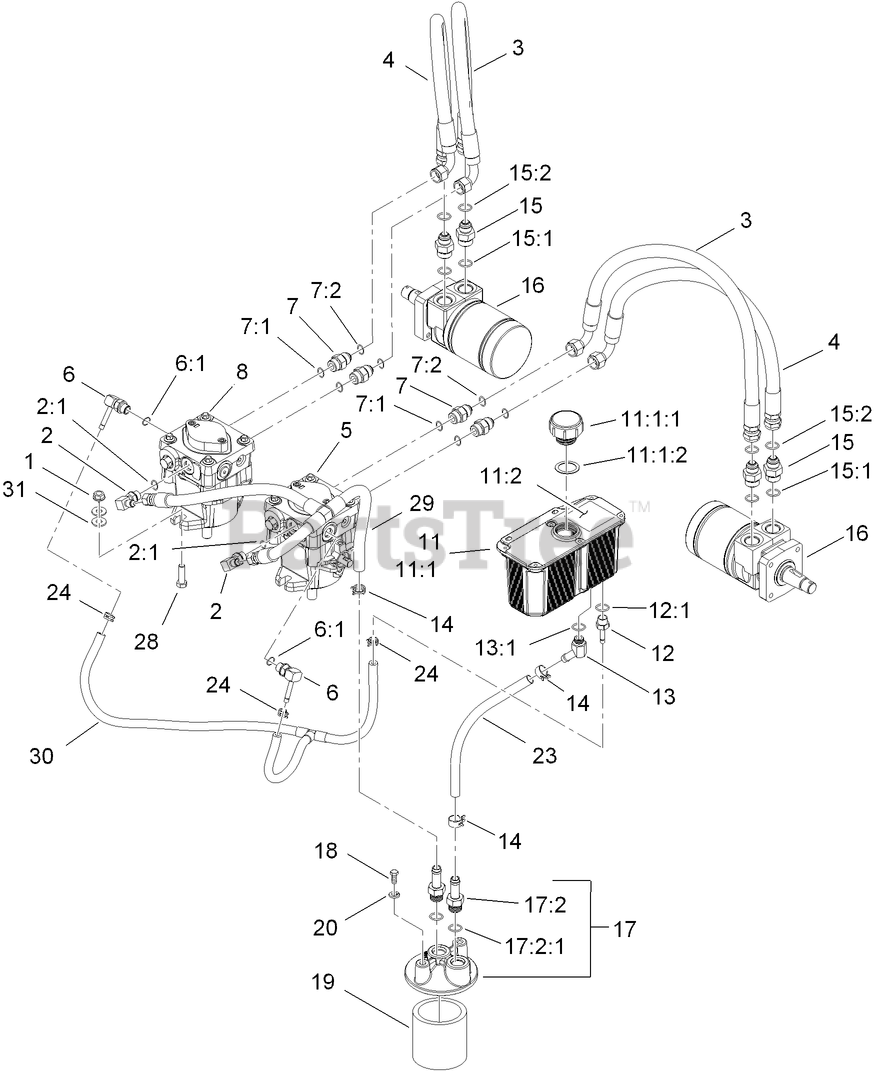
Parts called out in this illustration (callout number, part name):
1	NUT-HHF, WHIZ
2	FITTING-ELBOW, 90 DEG
2:1	O-Ring
3	HYD HOSE ASM
4	HYD HOSE ASM
5	PUMP-HYD
6	ELBOW-90 DEG
6:1	O-RING
7	FITTING-STRAIGHT
7:1	O-RING
7:2	O-Ring
8	PUMP-HYD
11	HYD RESERVOIR ASM
11:1	Reservoir-HYD
11:1:1	CAP-RESERVOIR, HYD
11:1:2	GASKET-CAP
11:2	DECAL-WARNING
12	Adapter-Straight
12:1	O-RING
13	FITTING-BARBED, 45 DEG
13:1	O-RING
14	Clamp-Hose
15	Fitting-Straight
15:1	O-RING
15:2	O-Ring
16	HYD MOTOR ASM
17	Filter Head ASM
17:2	ADAPTER-STRAIGHT
17:2:1	O-RING
18	SCREW-HH
19	FILTER-OIL, HYD
20	WASHER-LOCK
23	Hose-Charge
24	Clamp-Hose
28	SCREW-HH
29	CHARGE HOSE ASM
30	CASE DRAIN HOSE ASM
31	WASHER-FLAT
